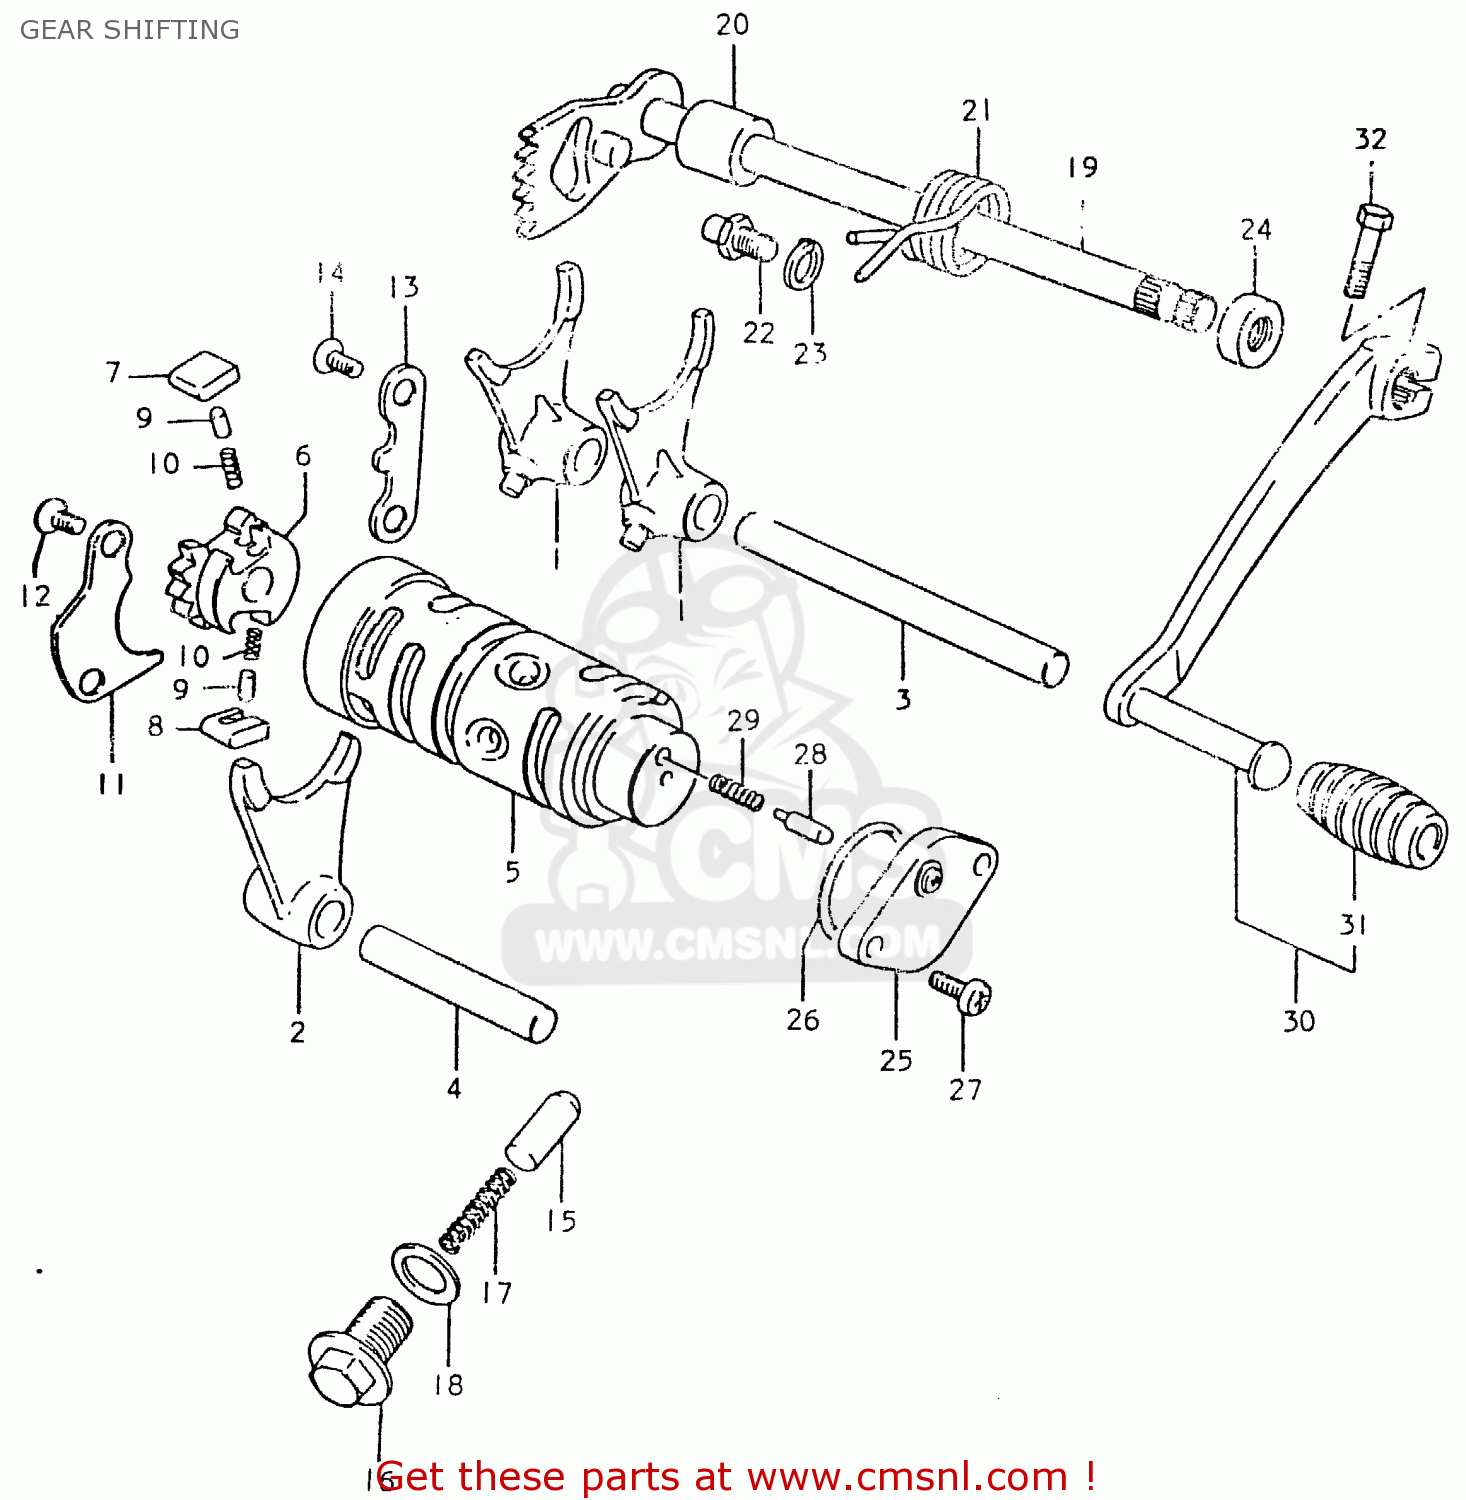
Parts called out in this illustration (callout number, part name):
1	FORK,GEAR SHIFT NO.1
2	FORK,GEAR SHIFT NO.2
3	SHAFT,GEAR SHIFT FORK
4	SHAFT,GEAR SHIFT FORK
5	CAM,GEAR SHIFT
6	RETAINER,GEAR SHIFT CAM
7	PAWL,GEAR SHIFT NO.1
8	PAWL,GEAR SHIFT NO.2
9	PIN(5X8)
10	SPRING
11	LIFTER,GEAR SHIFT PAWL
12	SCREW
13	GUIDE,GEAR SHIFTING CABLE
14	SCREW
15	STOPPER,GEAR SHIFTING
16	BOLT,GEAR SHAFT CAM STOPPER
17	SPRING
18	GASKET(14X19.2X2) (NAS)
19	SHAFT,GEAR SHIFT
20	SPACER(12X20X15.3)
21	SPRING
22	STOPPER,GEAR SHIFT CAM
23	WASHER
24	OIL SEAL
25	BODY,GEAR SHIFT SWITCH
26	O-RING (D:2.4 ID:26.2)
27	SCREW
28	PIN(5X15.5)
29	SPRING
30	LEVER ASSY,GEAR SHIFT
31	RUBBER,GEAR SHIFT PEDAL
32	BOLT
